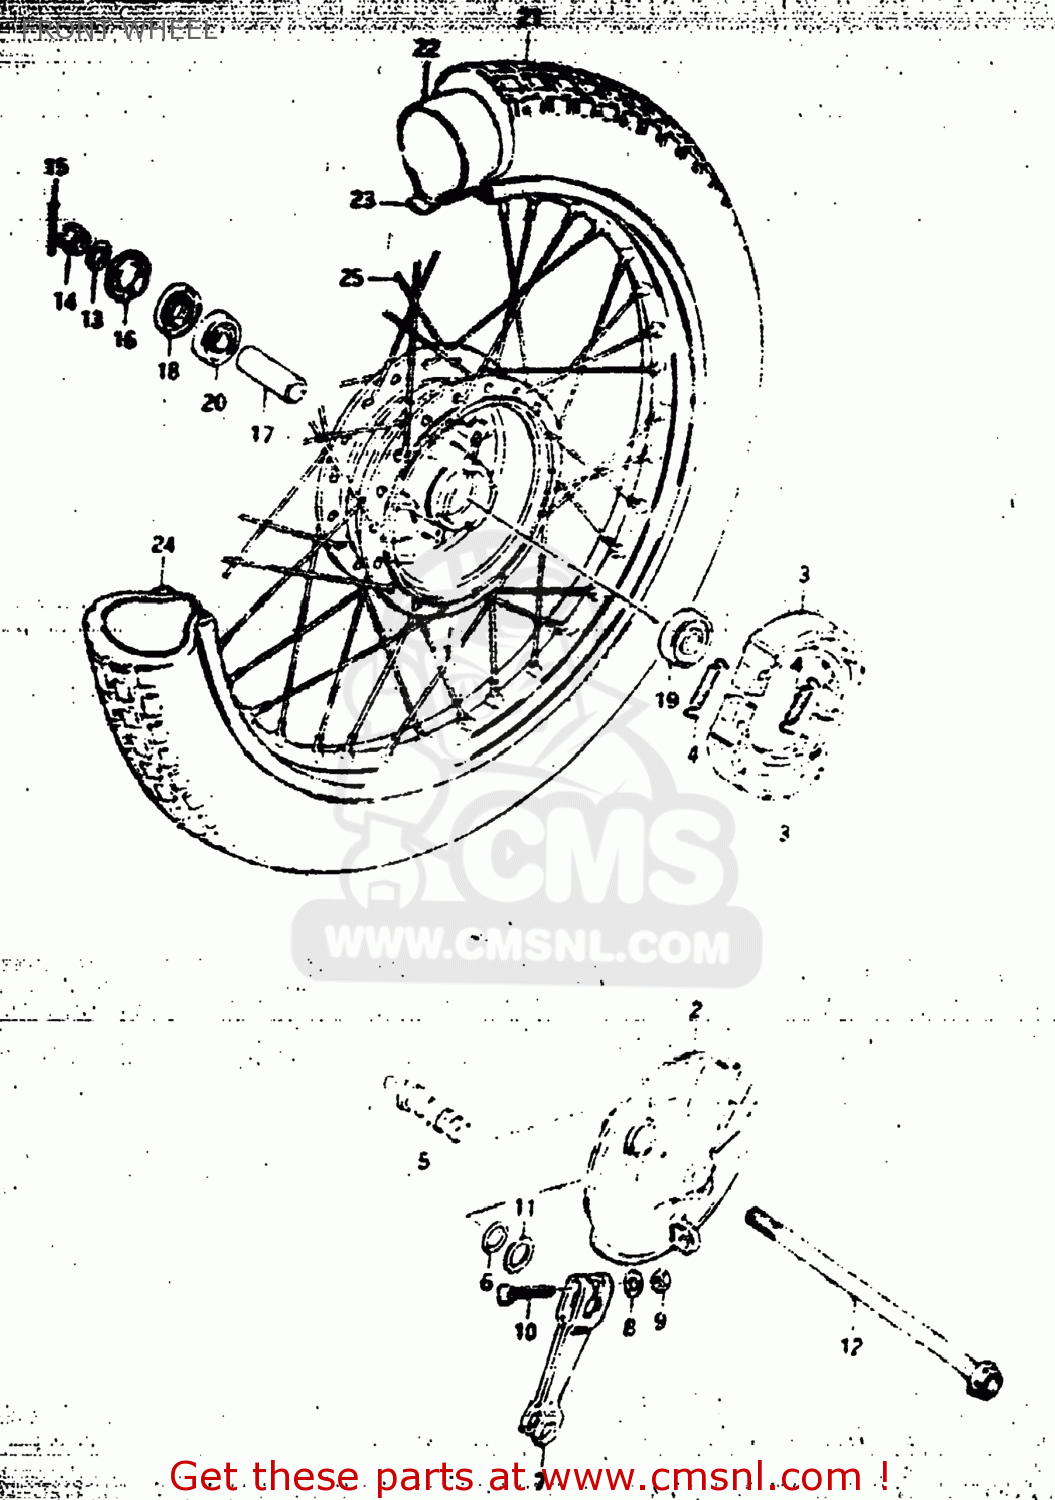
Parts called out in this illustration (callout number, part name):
1	HUB,FR
2	PANEL,FR BRAKE ANCHOR
3	SHOE,BRAKE (MCA)
4	SPRING(L:34)
5	CAM,FRONT BRAKE
6	O-RING (D:2.4 ID:13.8)
7	LEVER,FR BRAKE CAM
8	WASHER
9	NUT
10	BOLT 6X35
11	WASHER (14.5X22X1.6)
12	AXLE,FRONT
13	WASHER
14	NUT
15	PIN 20X20
16	SPACER,FRONT AXLE,RIGHT
17	SPACER (10.2X16X51)
18	SEAL,OIL(15X31X5)
19	BEARING
20	BEARING
21	TIRE(2.25 14)
22	TUBE,INNER
23	PROTECTOR,INNER TUBE
24	RIM,FR WHEEL(1.40X14)
25	SPOKE SET,FRONT
